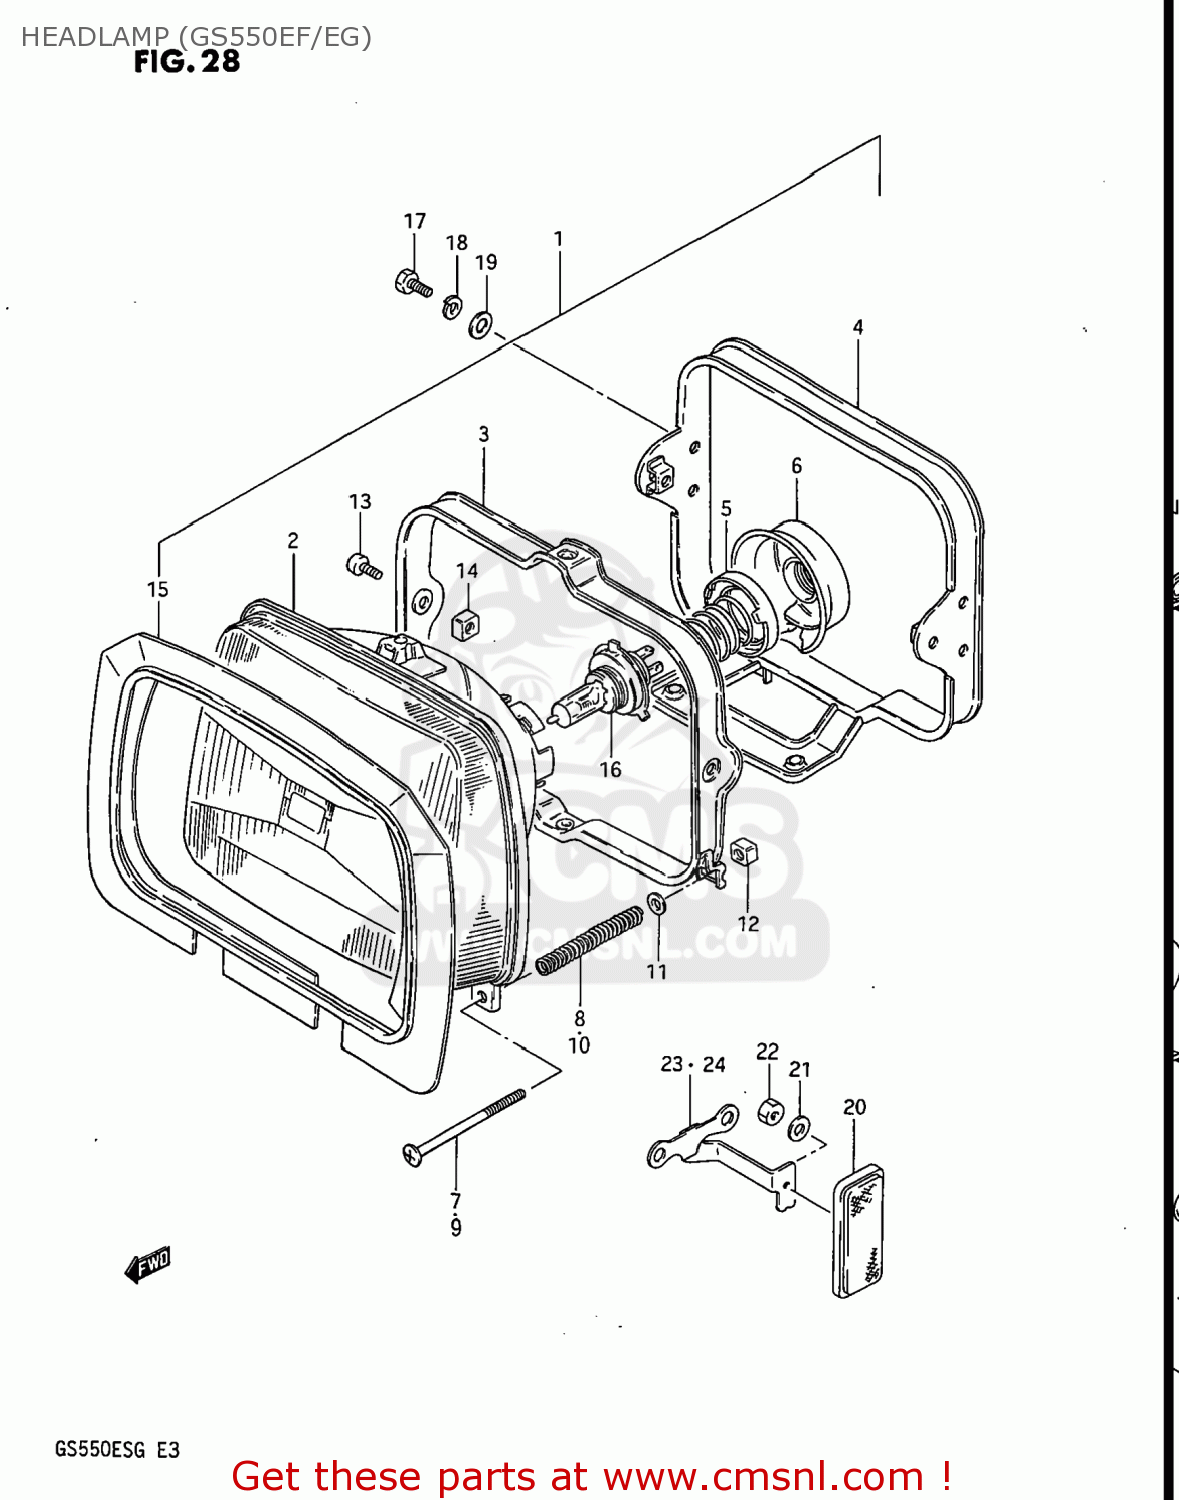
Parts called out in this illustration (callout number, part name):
1	LAMP ASSEMBLY,HEAD
2	LAMP UNIT
3	RING,MOUNTING
4	HOUSING
5	HOLDER
6	COVER,HEADLAMP SOCKET
7	SCREW,HEADLAMP ADJUST
8	SPRING
9	SCREW,HEADLAMP ADJUST
10	SPRING,HEADLAMP ADJUST
11	WASHER
12	NUT
13	SCREW
14	NUT
15	SHADE
16	BULB(12V60/55W,H4)
17	BOLT
18	WASHER,LOCK
19	WASHER, LOWER
20	REFLEX REFLECTOR,FR SIDE
21	WASHER,5MM
22	NUT ,5MM
23	BRACKET, RH
24	BRACKET, LH
